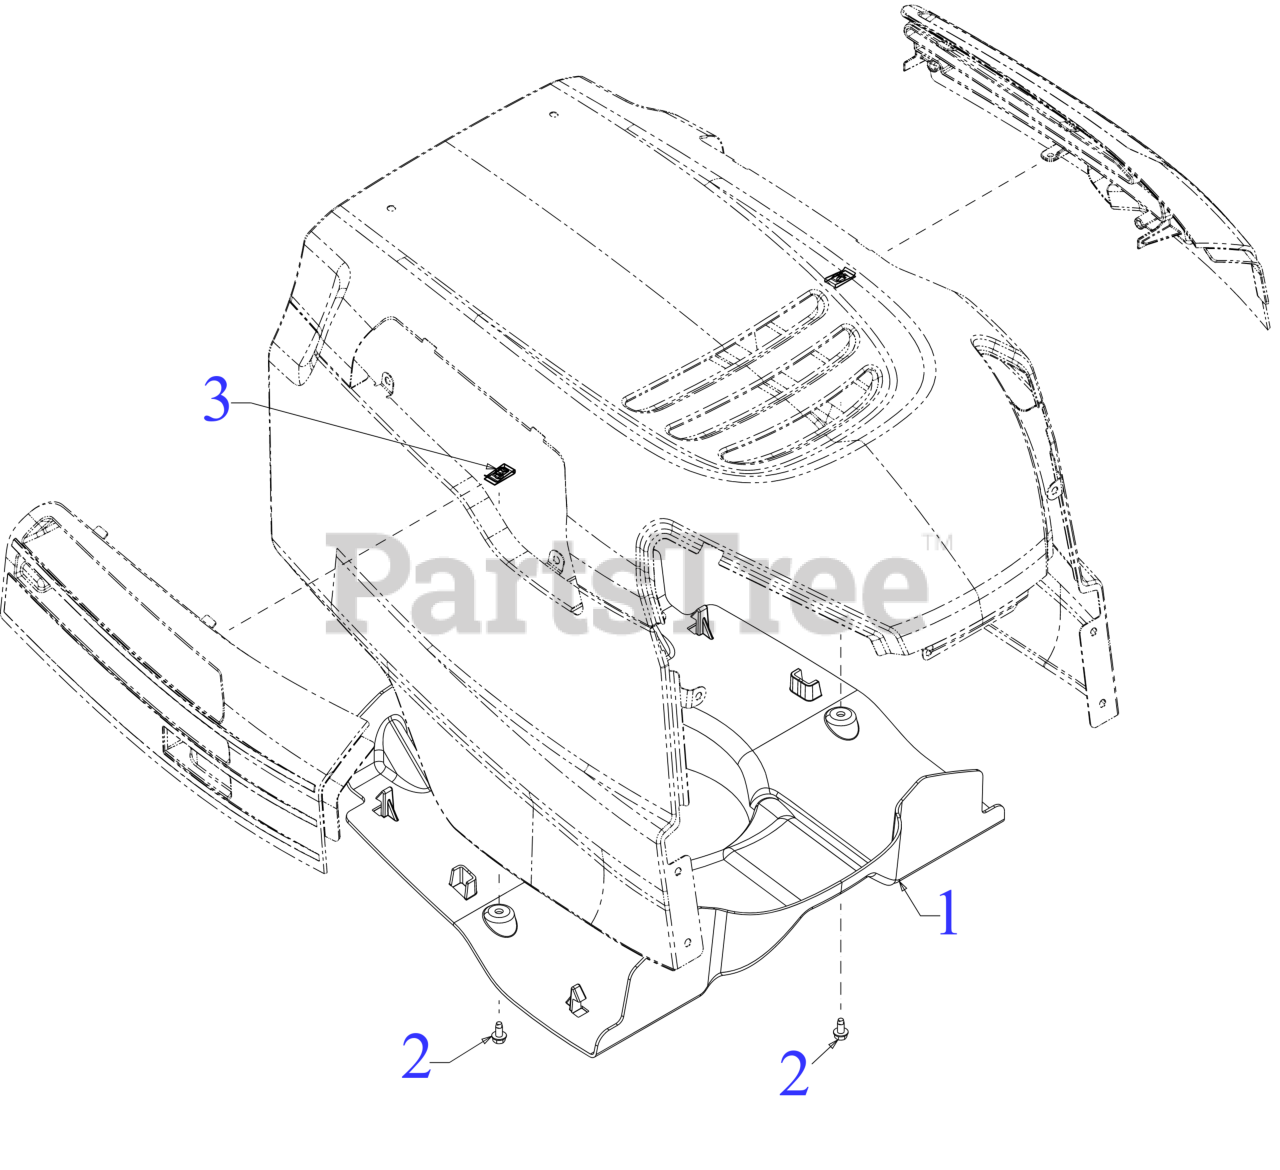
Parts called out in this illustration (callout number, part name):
1	HOOD PLENUM
2	SCREW 1/4-20 X.500
3	SPEED NUT
